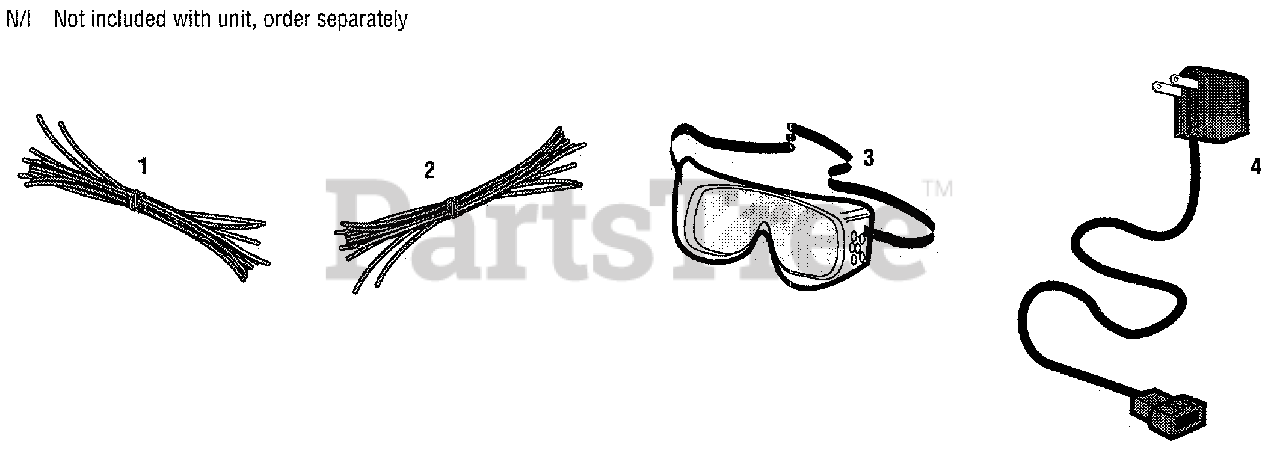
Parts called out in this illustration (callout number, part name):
1	Trimmer String Kit, .155"
2	Trimmer String Kit, .130"
3	Safety Goggles
4	Battery Charger
